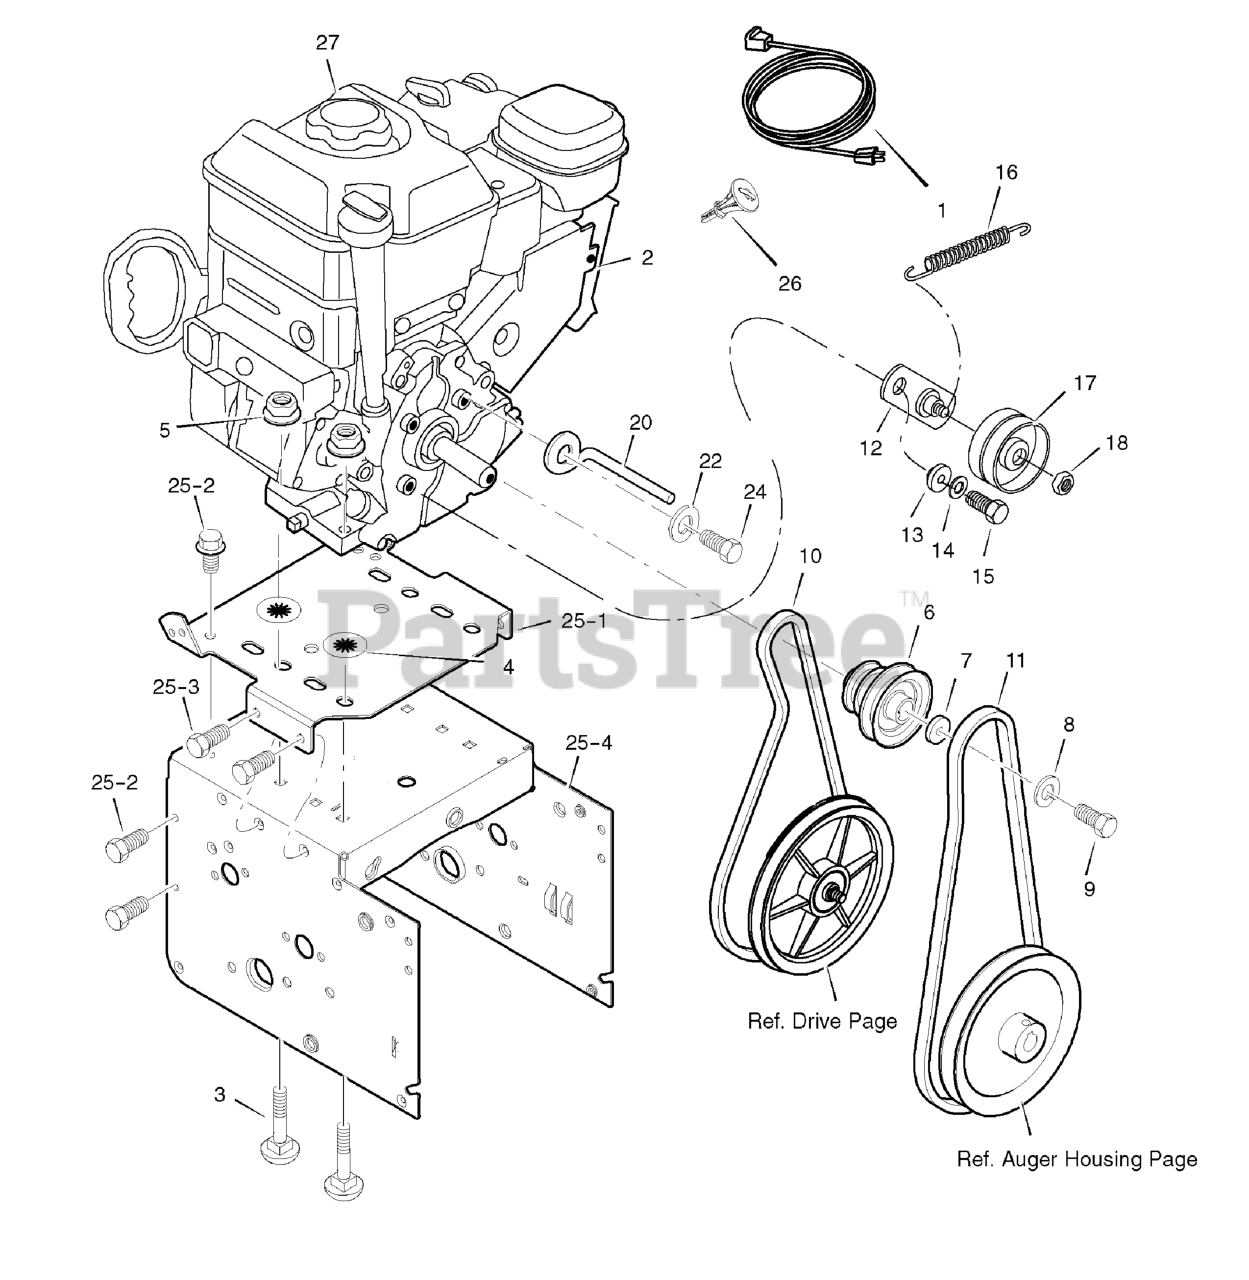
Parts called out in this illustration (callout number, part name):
1	CORD, Electric, 10FT. 110V
2	ENGINE
3	BOLT, CARRIAGE 5/16-18
4	RETAINER, PUSH
5	NUT 5/16-18
6	PULLEY, ENGINE
7	WASHER
8	WASHER .39ID
9	SCREW, 5/16-24 X 1.00
10	V-BELT, 3L, 33.13
11	BELT, V 4L
12	BRACKET ASSEMBLY, IDLER
13	BUSHING, IDLER BRACKET
14	WASHER, SPLIT
15	SCREW 5/16-24 X 0.75
16	SPRING, IDLER TRACTION DRIVE
17	PULLEY, IDLER
18	NUT, JAM 3/8-16
20	GUIDE, BELT
22	WASHER .31 X .58 X .08
24	SCREW, 5/16-24 X 0.75
25-1	PLATE, ENGINE MOUNT
25-2	SCREW, TAP 1/4-20 X .63
25-3	SCREW, TAP 5/16-18 X .50
25-4	FRAME, MOTOR BOX
26	KEY, BRIGGS ENGINE
27	CAP, GAS
